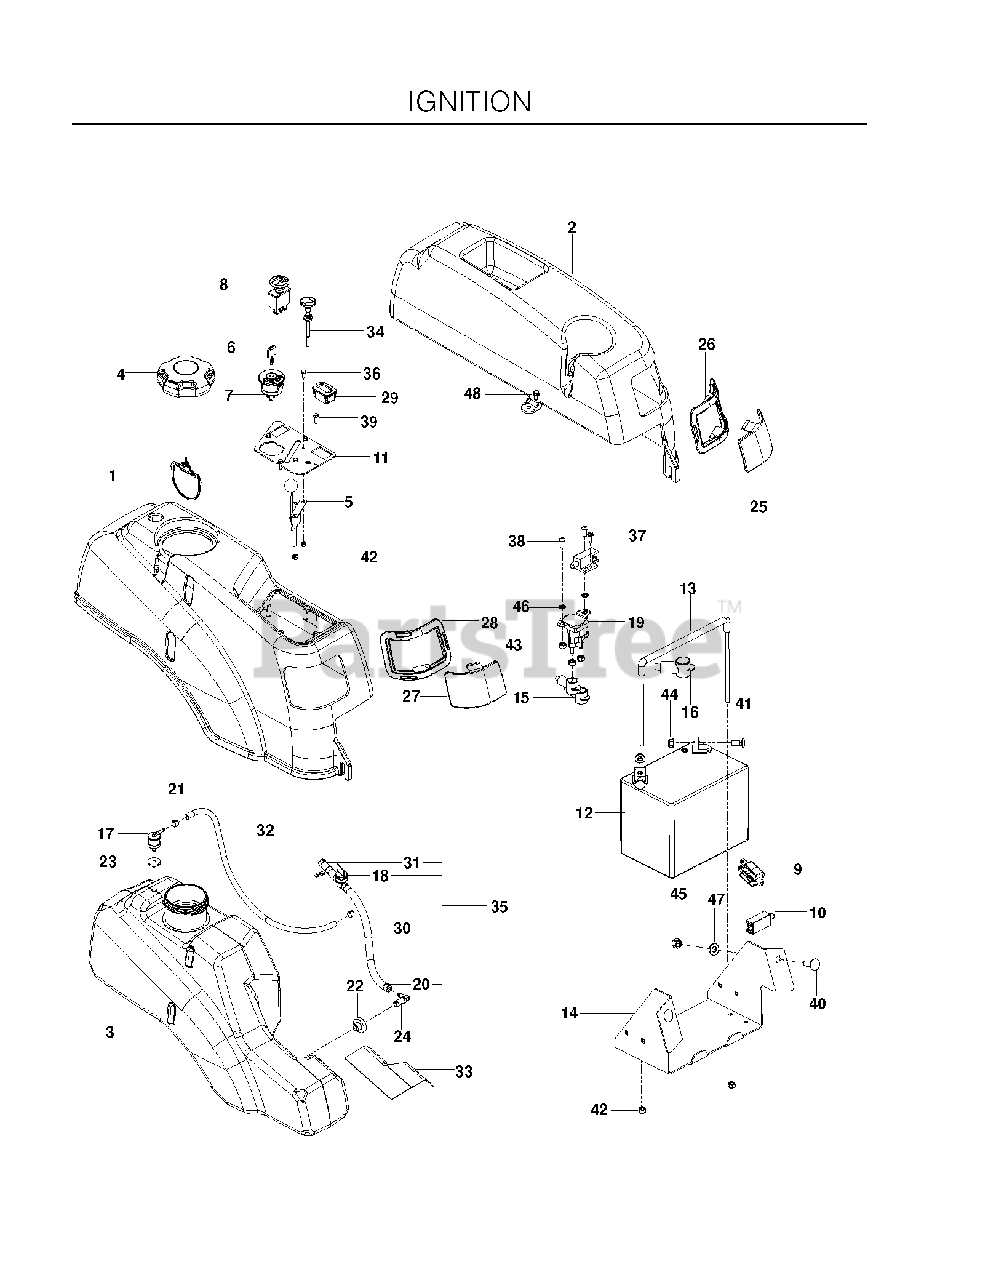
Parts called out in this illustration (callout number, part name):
1	FENDER, RT, BLK
2	FENDER, LT, BLK
4	CAP, FUEL
5	THROTTLE CABLE
7	IGNITION SWITCH
8	SWITCH, BLADE
9	SWITCH, BRAKE 3P
10	SWITCH, INTERLOCK
13	BATTERY TIE DOWN ASSEMBLY
14	BOX, BATTERY, BLACK
15	TERMINAL COVER-SM
16	INSULATOR
17	VALVE.FUEL.CHECK
18	FUEL VALVE
19	SOLENOID
20	HOSE CLAMP
21	CLAMP, HOSE
22	RUBBER GROMMET
23	GROMMET, CHECK VALVE
25	PANEL, LT
26	RING, LT BLK
27	PANEL, RT, BLK
28	RING, TRIM, RT-BLK
29	HOUR METER
30	GAS LINE 10"
31	FUEL LINE 2.5"
32	HOSE, FUEL, 3/16" X 20"
34	CHOKE CABLE
35	FUEL LINE ASSY
36	HCS #10-24 X 1/2
37	SCREW #10 X 1/2 SELF TAPPING
38	SCR 1/4-20 X 5/8 BTN SKT HD ZD
39	SCR #10-12X3/4 HEX WAS HD ZD
40	RHSNB 3/8C X 1
41	BOLT 5/16C X 3/4" CARRIAGE
42	NUT 10-24 NYLOC
43	NUT 1/4-20 NYLOC
44	5/16-18 NYLOC FLANGE NUT
45	NUT 3/8-16 NYLOC
46	WASHER 1/4 INT TOOTH
47	WASHER 3/8 SAE FLAT
48	BOLT 1/4-20 X 1/2 HWST
